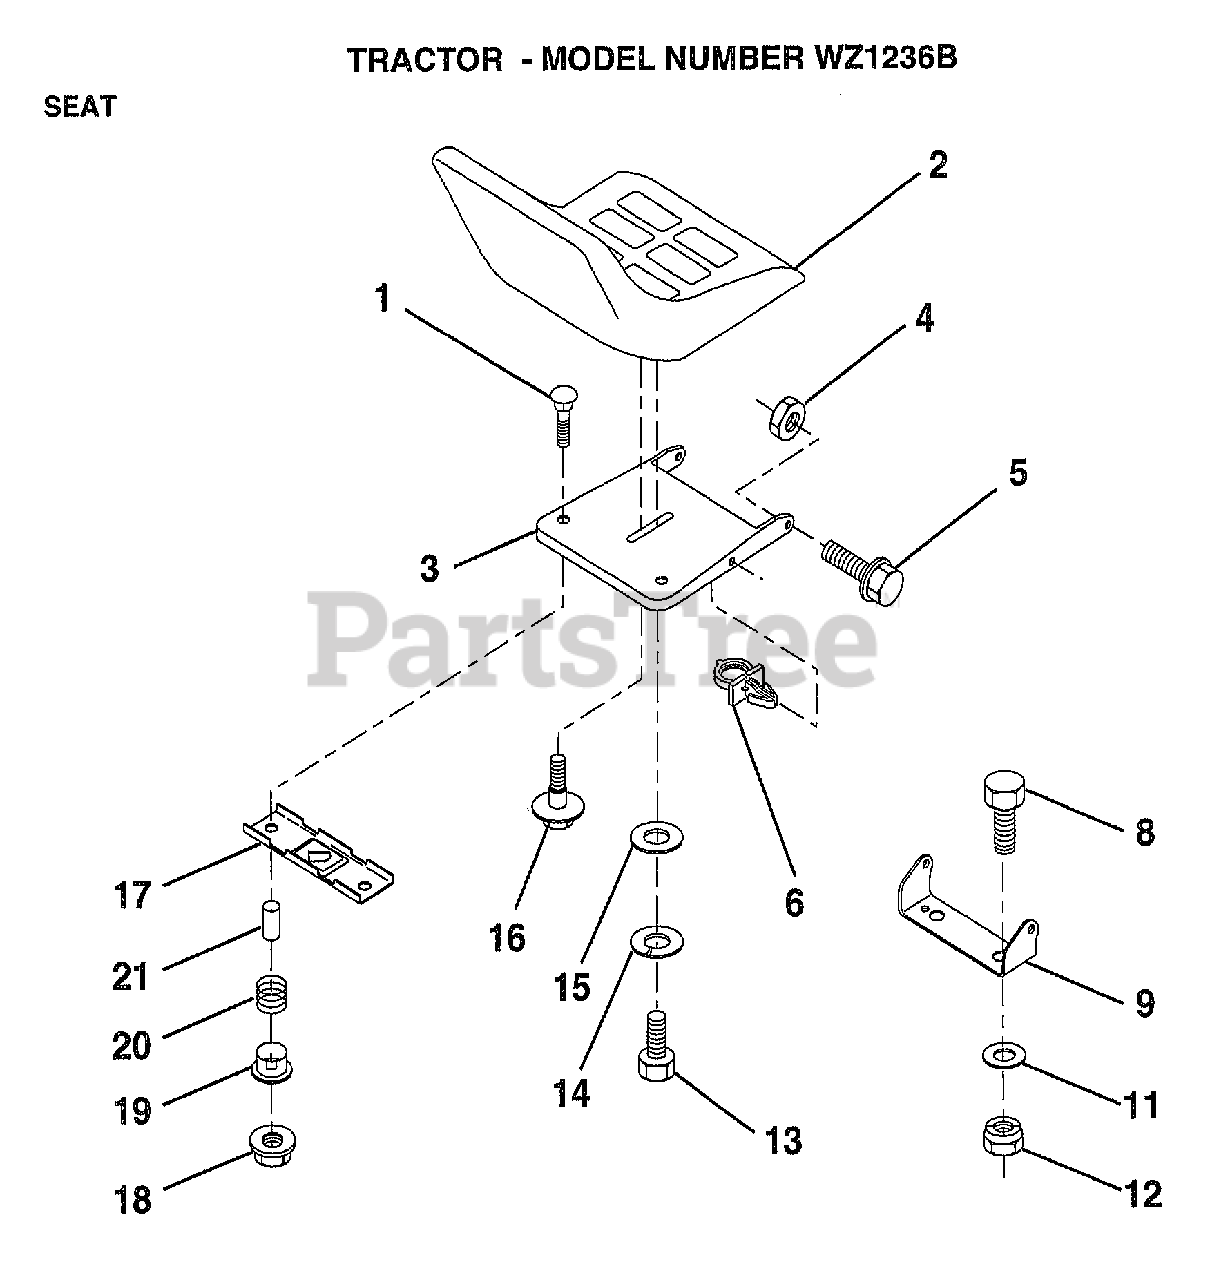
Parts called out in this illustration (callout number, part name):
1	BOLT-RD HD SQ NK
3	PAN-SEAT
4	NUT
5	"BOLT,SHOULDER"
6	CLIP.PUSH-IN.HING
8	BOLT
9	BRACKET PVT SEAT
11	WASHER
12	NUT
13	BOLT
14	LOCKWASHER
15	WASHER
16	"BOLT,SHOULDER"
17	BRKT SWITCH
19	BUSHING
20	SPRING
21	SPLIT SPACER
